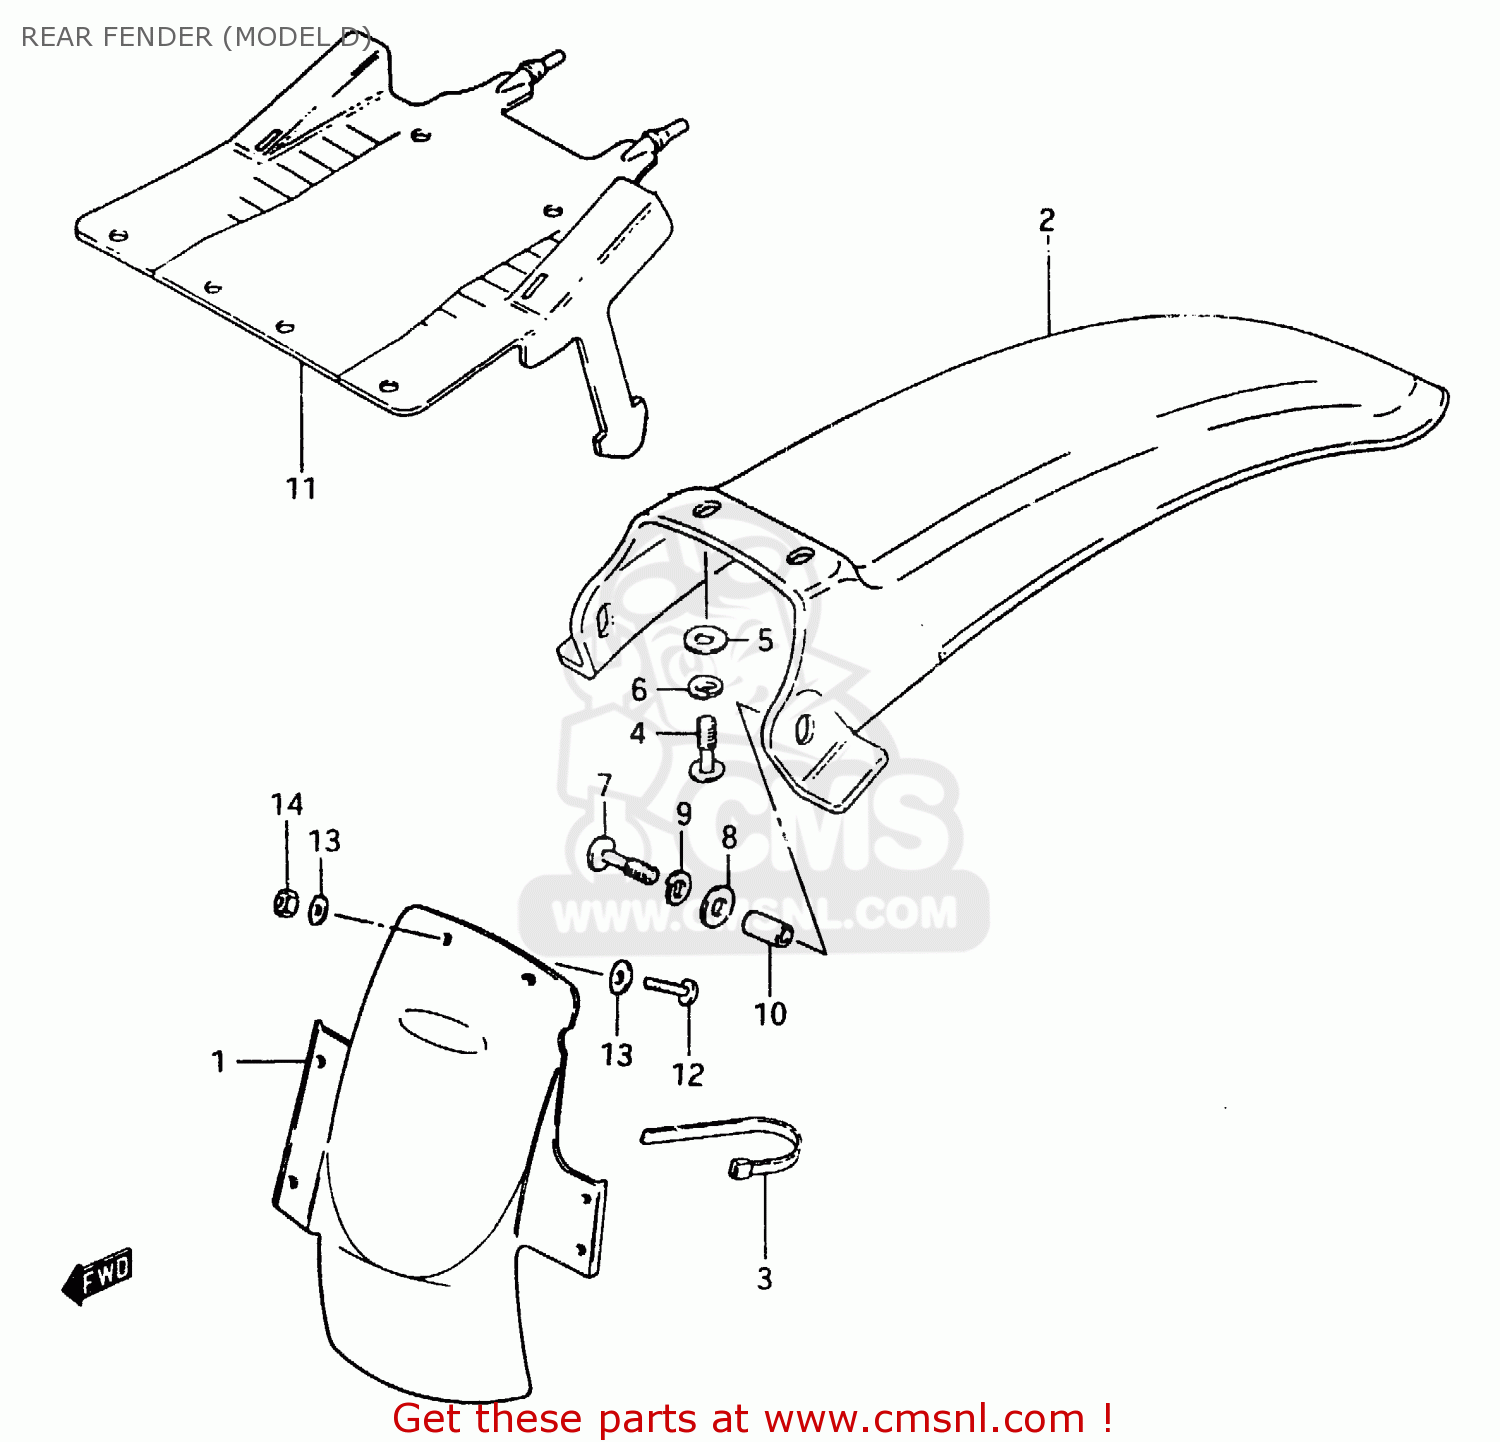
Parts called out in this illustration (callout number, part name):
1	FENDER,REAR
2	FENDER,REAR
3	CLAMP
4	SCREW
5	WASHER
6	LOCK WASHER
7	BOLT, UPPER
8	WASHER (6.5X20X1.2)
9	LOCK WASHER
10	SPACER
11	GUIDE,RR FENDER MUD
12	SCREW
13	WASHER
14	NUT
